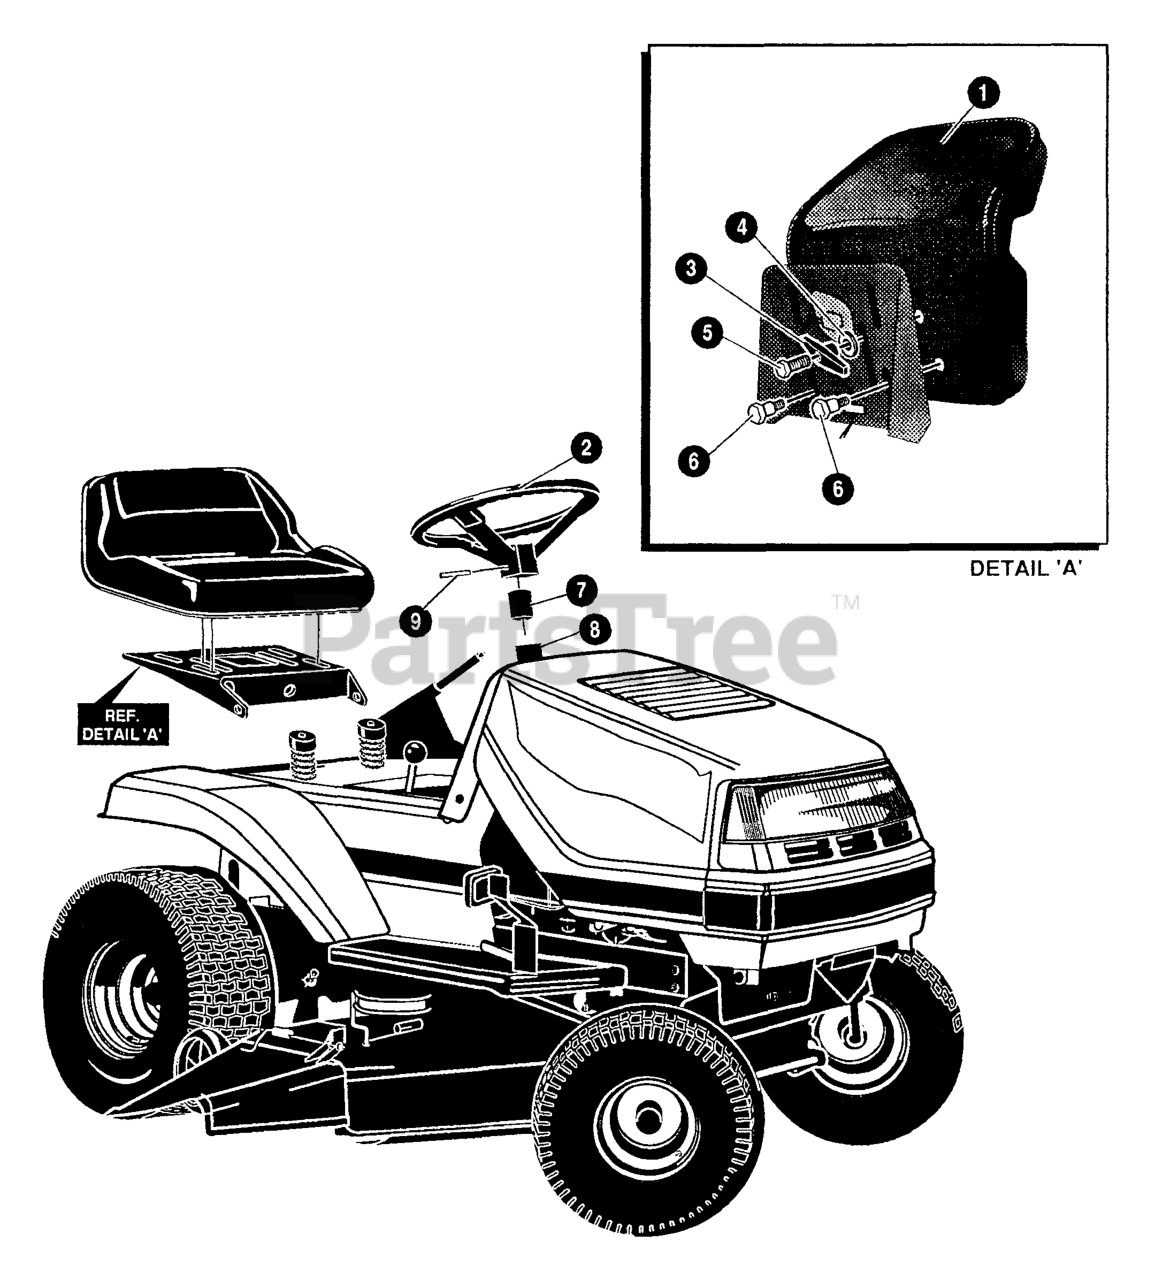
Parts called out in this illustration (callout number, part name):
2	STEERING WHEEL
3	HANDLE, WING NUT BLACK
4	WASHER, FLAT .344 X .69 X .065
5	SCREW, 5/16-18 x 1.00
6	BOLT, .500 X .10
7	COVER, STEERING SHAFT
8	SPACER, STEERING SHAFT
9	PIN, SPRING
